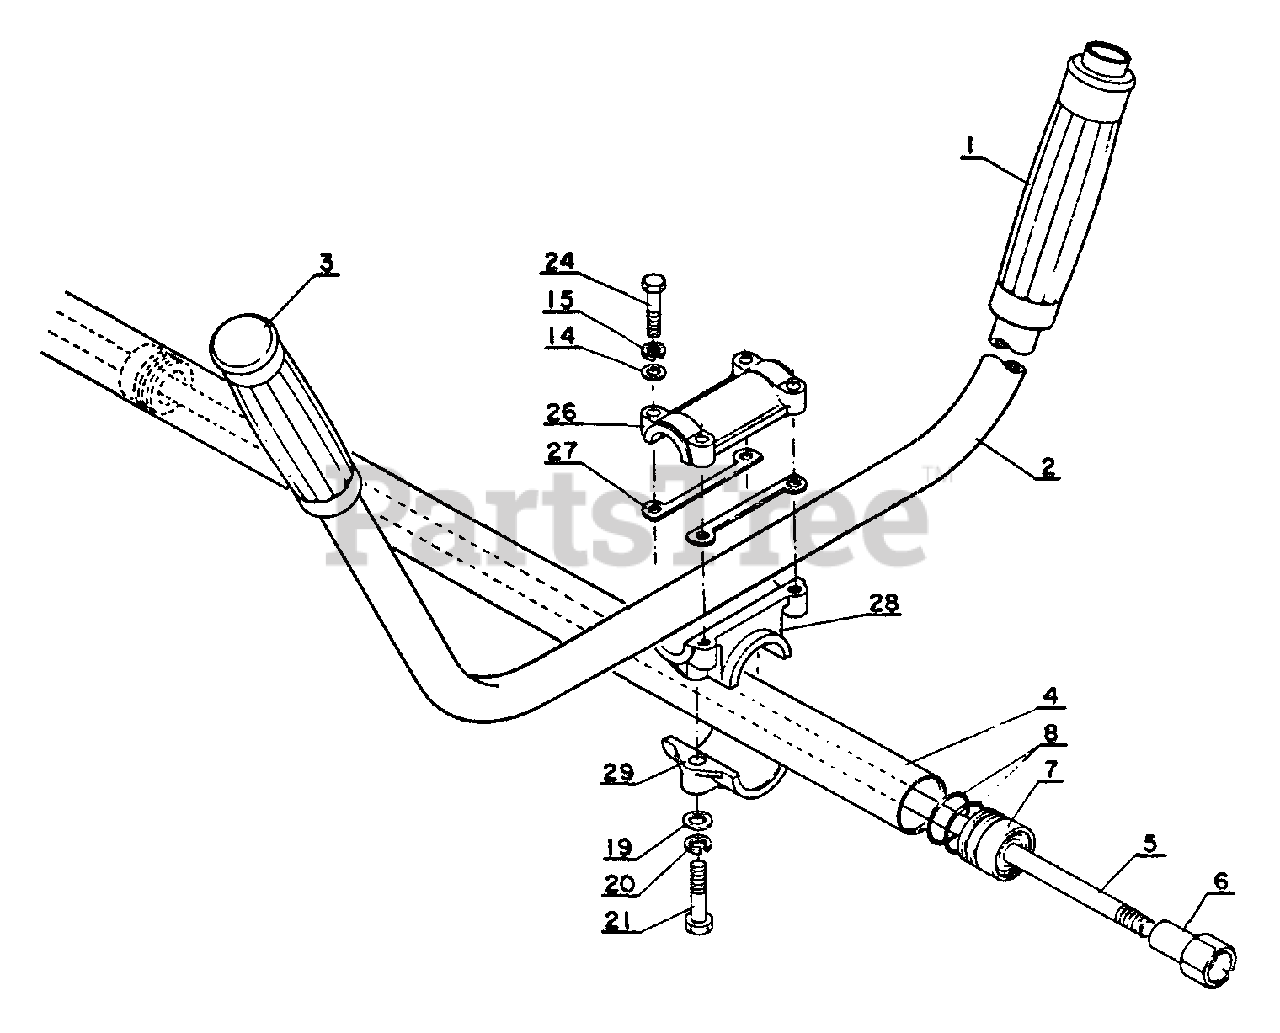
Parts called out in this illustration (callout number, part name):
1	GRIP, HANDLE
2	U-HANDLE
3	GRIP, HANDLE
4	MAIN PIPE ASSY
5	DRIVESHAFT
7	STOPPER
8	O-RING 22
19	WASHER 6.5×11.5×0.8
20	WASHER, SPRING 6
21	BOLT - 6×32
24	BOLT - 5×25
26	BRACKET ASSY, HANDLE
28	BRACKET ASSY, HANDLE
29	BRACKET ASSY, HANDLE
